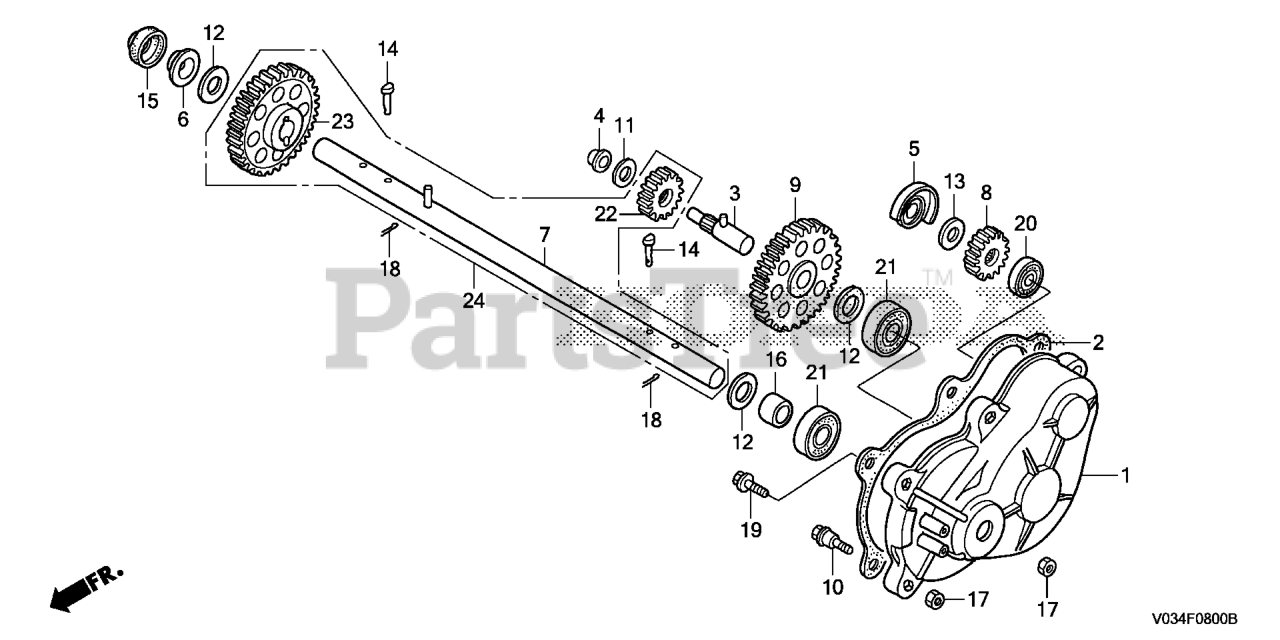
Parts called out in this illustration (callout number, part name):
1	CASE, R. TRANSMISSION
2	GASKET, TRANSMISSION CASE
3	COUNTERSHAFT
4	BUSH, COUNTERSHAFT
5	BUSH, CROSS SHAFT
6	BUSH, FINAL SHAFT
7	GEAR SET, FINAL
7	SHAFT, WHEEL
8	GEAR, DRIVE (19T)
9	GEAR, DRIVEN (48T)
10	BOLT, TRANSMISSION SETTING
11	WASHER, THRUST (12MM)
12	WASHER, DIFFERENTIAL GEAR
13	WASHER, THRUST (15X24X2)
15	DUST SEAL (20X34X7.5)
16	COLLAR, WHEEL SHAFT
17	NUT, HEX. (6MM)
18	PIN, SPLIT (3.0X25)
18	PIN, COTTER (3.0X45)
19	BOLT, FLANGE (6X18)
20	BEARING, RADIAL BALL (6002UU)
21	BEARING, RADIAL BALL (6004UU)
22	GEAR, FINAL DRIVE (15T)
22	GEAR, DRIVE (19T)
23	GEAR, DRIVEN (48T)
23	GEAR, FINAL DRIVEN (38T)
24	GEAR SET, FINAL
